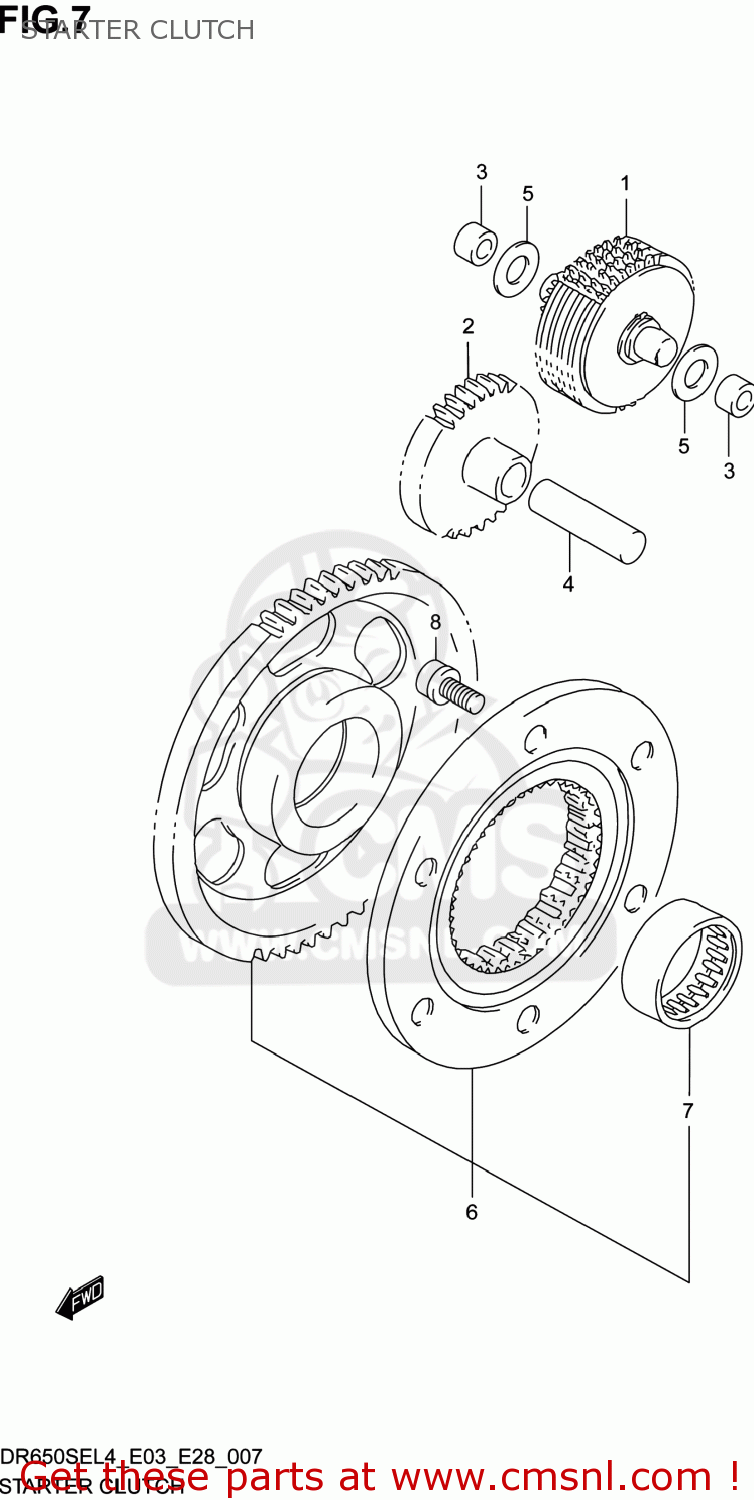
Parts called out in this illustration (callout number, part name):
1	LIMITER ASSY,STARTER IDLE GEAR
2	GEAR,STARTER IDLE NO.2(NT:27)
3	BUSH,LIMITER GEAR SHAFT
4	PIN
5	WASHER
6	CLUTCH SET,STARTER
7	BEARING(31X39X17.8)
8	BOLT(8X20)
